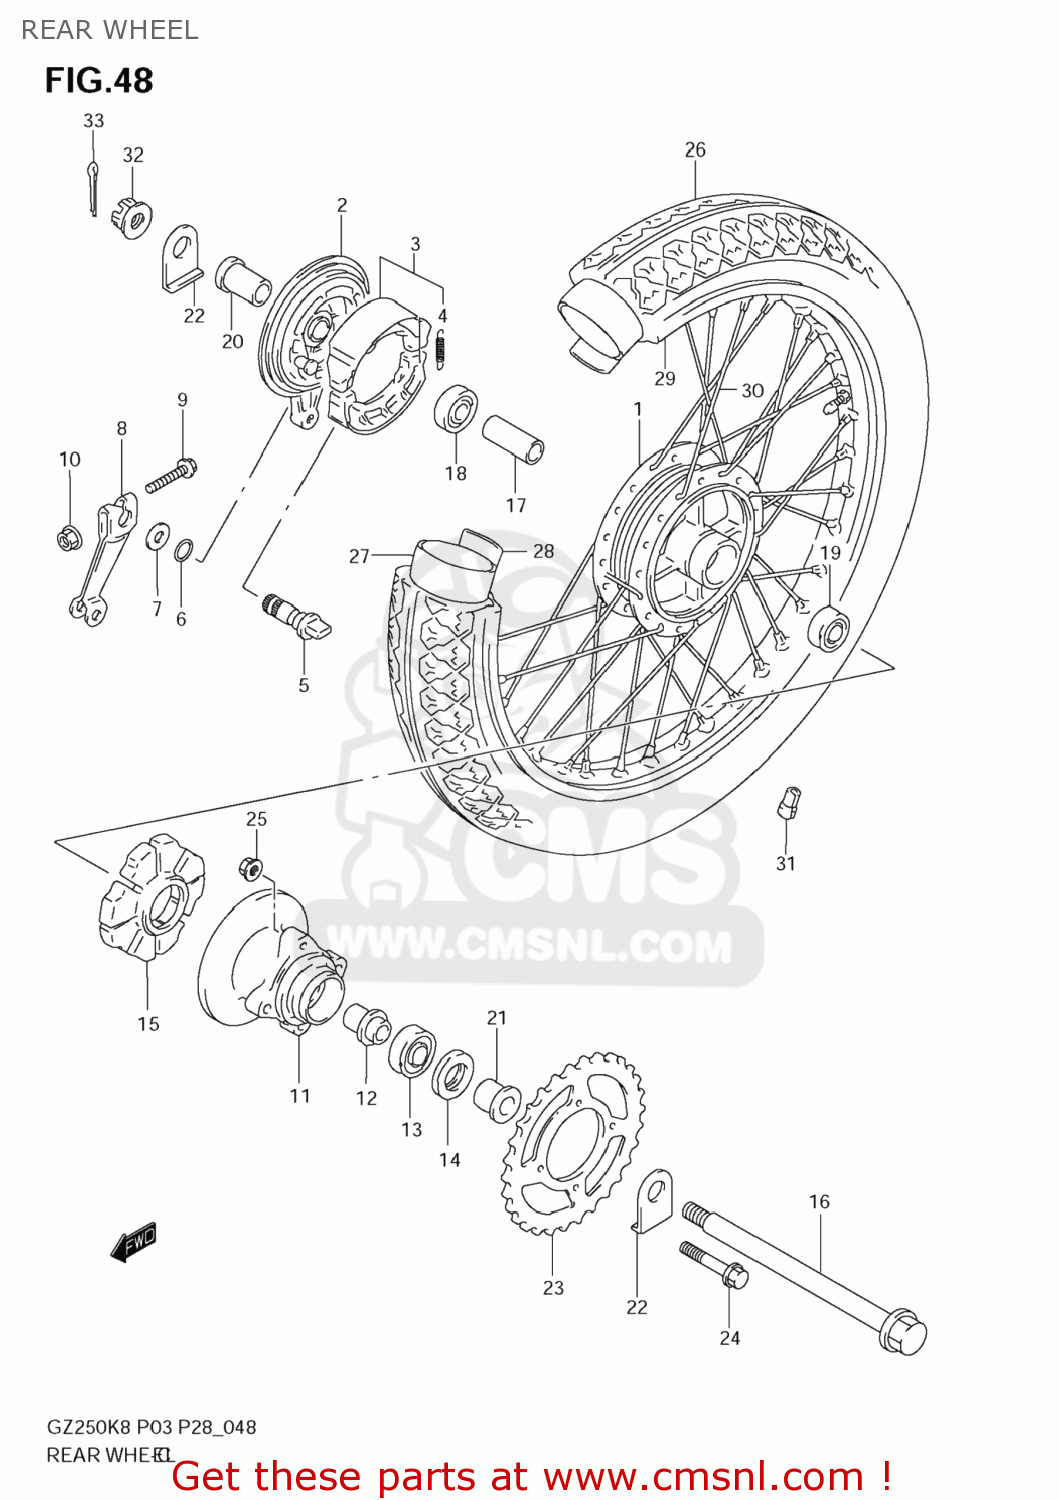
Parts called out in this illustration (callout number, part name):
1	HUB,RR WHEEL
2	PANEL,RR BRAKE ANCHOR
3	SHOE,BRAKE
4	SPRING(L:34)
5	CAM,BRAKE
6	O-RING (D:2.4 ID:13.8)
7	WASHER(14.5X22X1.6)
8	LEVER,RR BRAKE CAM
9	BOLT
10	NUT
11	DRUM,RR SPROCKET MOUNTING
12	RETAINER,RR SPROCKET DRUM
13	BEARING(20X47X14)
14	SEAL,OIL(28X47X7)
15	ABSORBER ASSY,HUB SHOCK
16	AXLE,RR
17	SPACER(15.3X21.7X63)
18	BEARING
19	BEARING
20	SPACER, AXLE RH
21	SPACER, AXLE LH
22	WASHER,CHAIN ADJUSTER GUIDE
23	SPROCKET NICHT
24	BOLT(10X40)
25	NUT
26	TIRE,RR(130/90,
27	TUBE ASSY, WHL
28	PROTECTOR, INNER TUBE
29	RIM,RR WHEEL(15XMT3.00)
30	SPOKE SET,RR WHEEL
31	BALANCER,WHEEL(15G)
32	NUT
33	PIN
